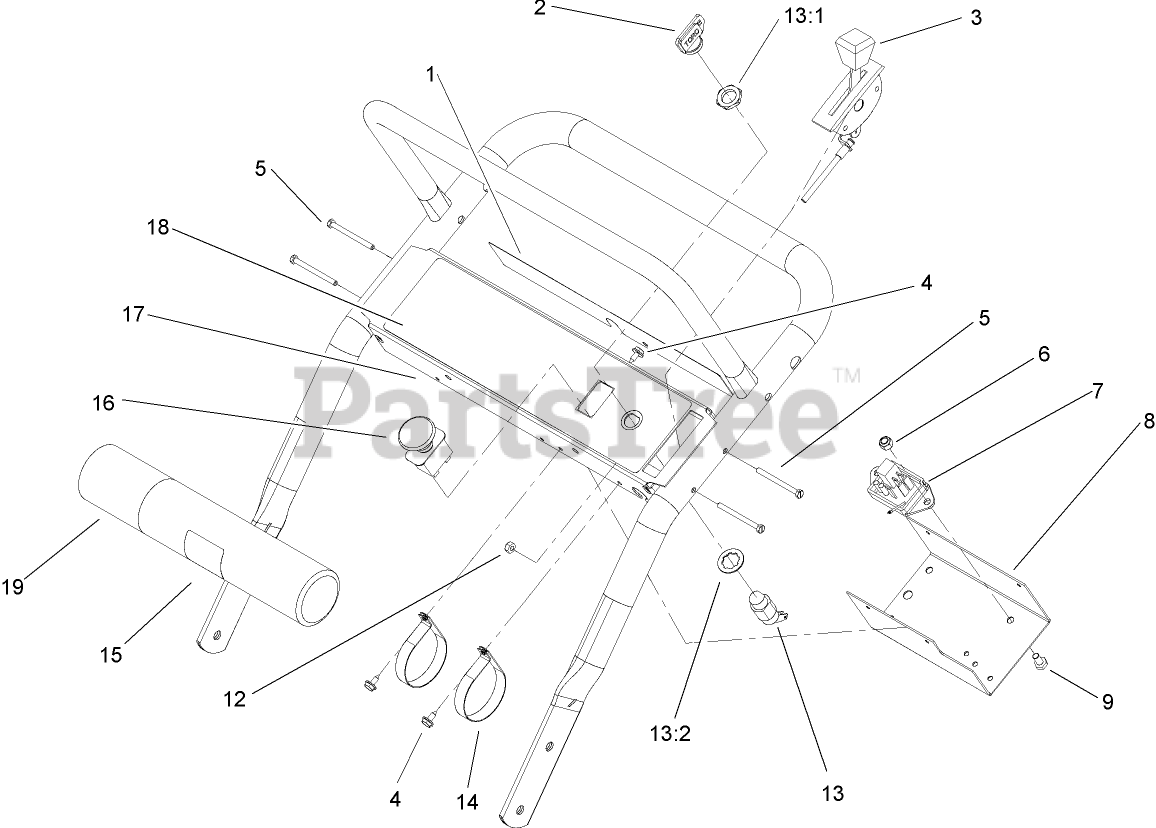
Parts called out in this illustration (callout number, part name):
1	DECAL-DANGER
2	KEY-IGNITION
3	CABLE-THROTTLE
4	SCREW-HWHTF
5	SCREW-SHH
6	NUT-LOCK, NI
7	MODULE-DELAY
8	PANEL-BOTTOM
9	SCREW-HH
12	NUT-LOCK, NI
13	SWITCH-ON / OFF
13:1	NUT-HH
13:2	WASHER-TOOTH, INTERNAL
14	CLAMP-R
15	TUBE-MANUAL
16	SWITCH-PTO
17	PANEL-CONTROL
18	DECAL-CONTROL PANEL
19	CAP-HOUSING
